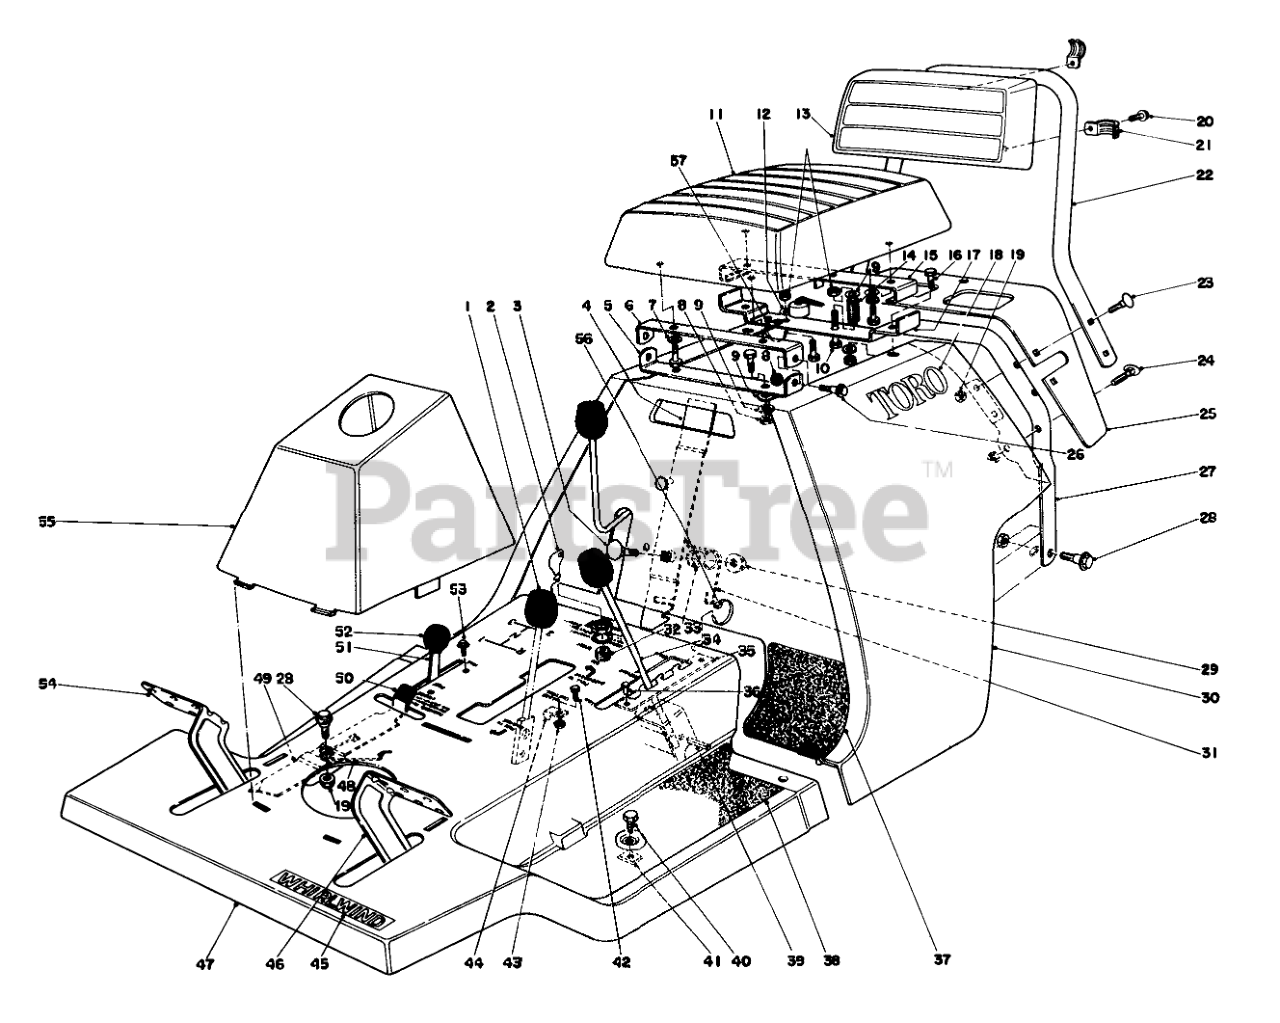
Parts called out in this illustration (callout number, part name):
2	Key
3	BOLT-CARR
4	Handle Latch
5	Seat Pivot Brkt-Lower
6	Seat Pivot Brkt-Upper
7	WASHER-LOCK
8	NUT-LOCK, CONE
9	WASHER-FLAT
10	SCREW-HH
12	SEAT SWITCH
13	Backrest
14	Spring
15	Rear Support Seat
16	SCREW-HH
17	Seat Support Rear Lower
18	TORO LOGO DECAL
19	NUT-LOCK, CONE
20	SCREW-HHF
21	CLAMP-CONDUIT
22	Handle Upper
23	SCREW-CARR
24	HANDLE SCREW
25	Extension Rear Body
26	SCREW-SHOULDER
27	Handle Lower
28	SCREW-SHOULDER
29	NUT-HF
30	Rear Body
31	Latch Return Spring
32	STARTER SWITCH
33	Spacer
34	Height of Cut Lever
35	Height Adjustment Plate
37	Heel Pad-LH.
38	Foot Tread LH.
39	PIN-SPECIAL
40	SCREW-HH
41	NUT-TINNERMAN
43	NUT-KEPS
44	CABLE CLAMP
45	WW DECAL
46	Clutch Pedal
47	Body Front (Incl. Ref. #35 & 36)
48	SPRING-PARKING BRAKE
49	Parking Brake
50	TIP-PARKING BRAKE
51	Throttle Control (Incl. Ref #52)
53	8X1/2 SELF TAP SCREW
54	Brake Pedal
55	Tower
56	TIE-CABLE
57	TIE-CABLE
